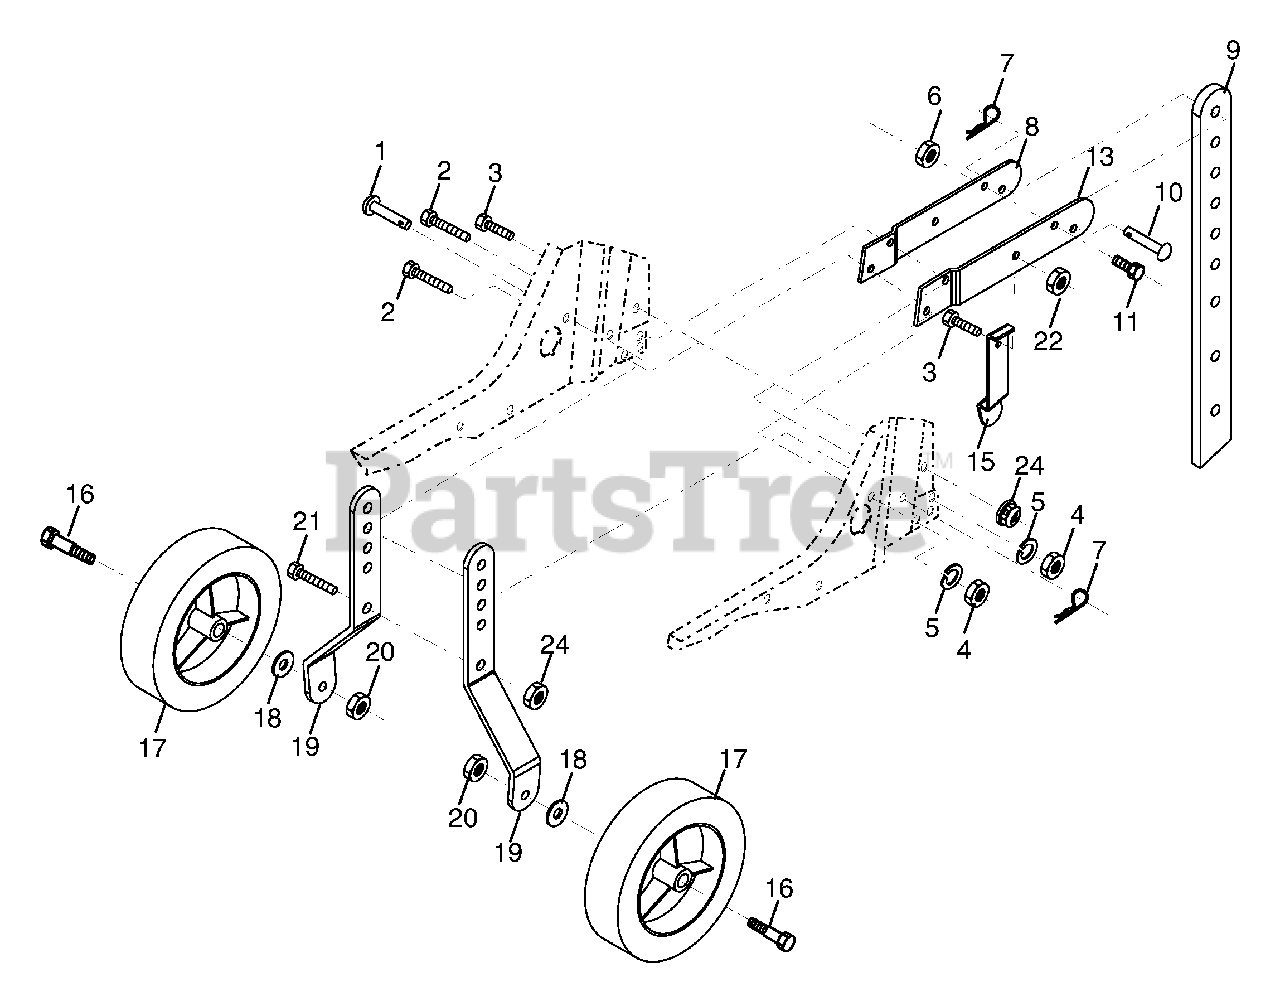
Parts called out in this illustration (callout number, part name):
1	Pin, Clevis
2	Bolt, Hex 5/16-18 x 1-1/4
3	Bolt, Hex 5/16-18 x 3/4
4	Nut, Hex 5/16-18
5	Washer, Lock 5/16
6	Locknut, w/washer 3/8-16
7	Clip, Hairpin
8	Support, Depth Stake, R.H.
9	Stake, Depth
10	Pin, Clevis
11	Bolt, Hex, Fin 3/8-16 x 1-3/4
13	Support, Depth Stake, L.H.
15	Spring, Stake
16	Bolt, Shoulder
18	Washer 13/32 x 13/16 x 11 Ga.
19	Bracket, Wheel
20	Locknut, Crown 3/8-16
21	Bolt, Hex 5/16-18 x 1
22	Locknut, w/insert 5/16-18
24	Nut Lock Hex Flange
